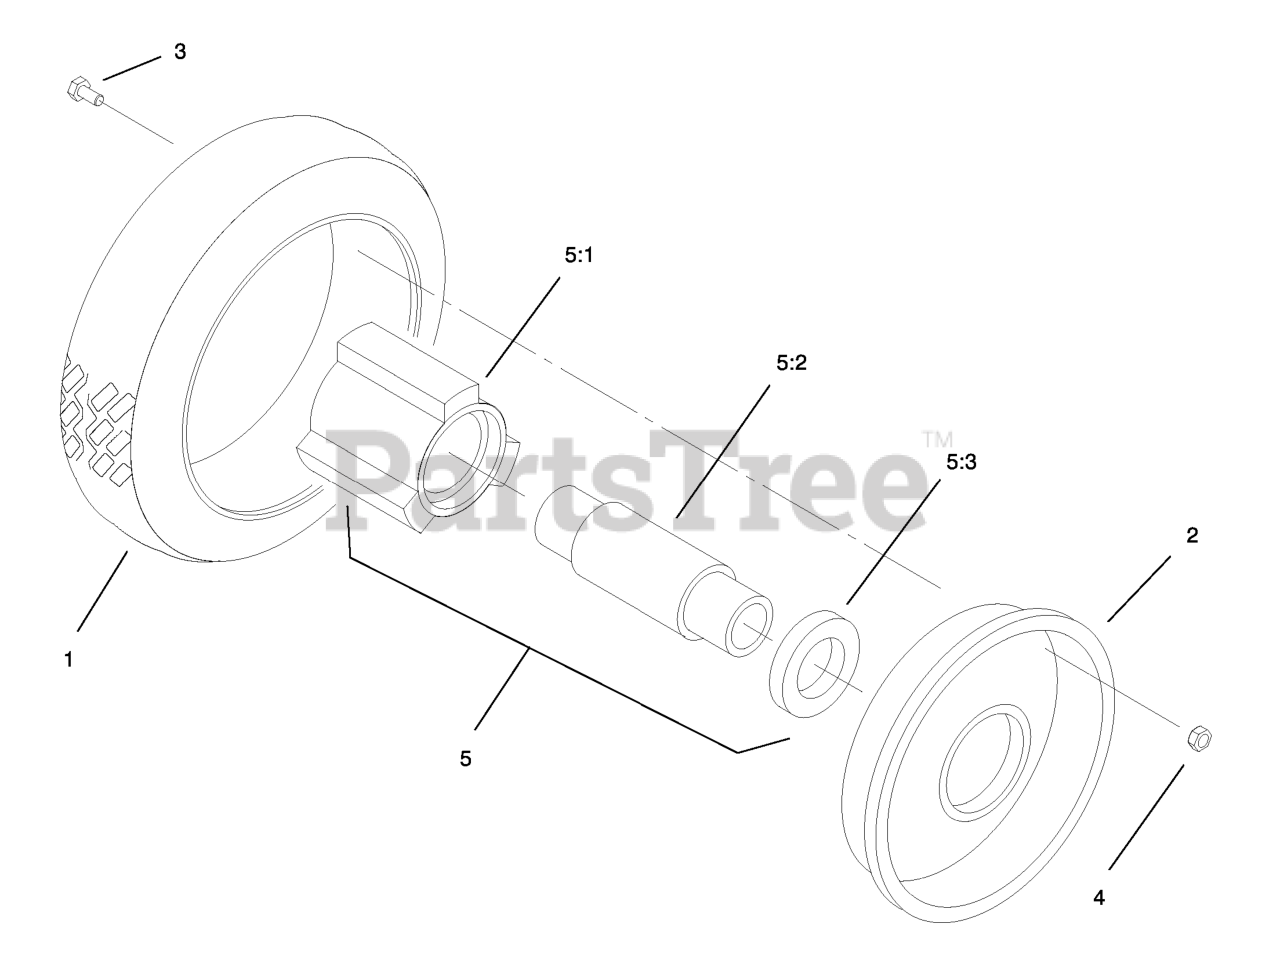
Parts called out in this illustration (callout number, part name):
3	SCREW-HH
4	NUT-LOCK, NI
5	Hub & Bearing Asm
5:1	HUB-BEARING
5:2	SPACER-BEARING
5:3	BEARING-WHEEL
